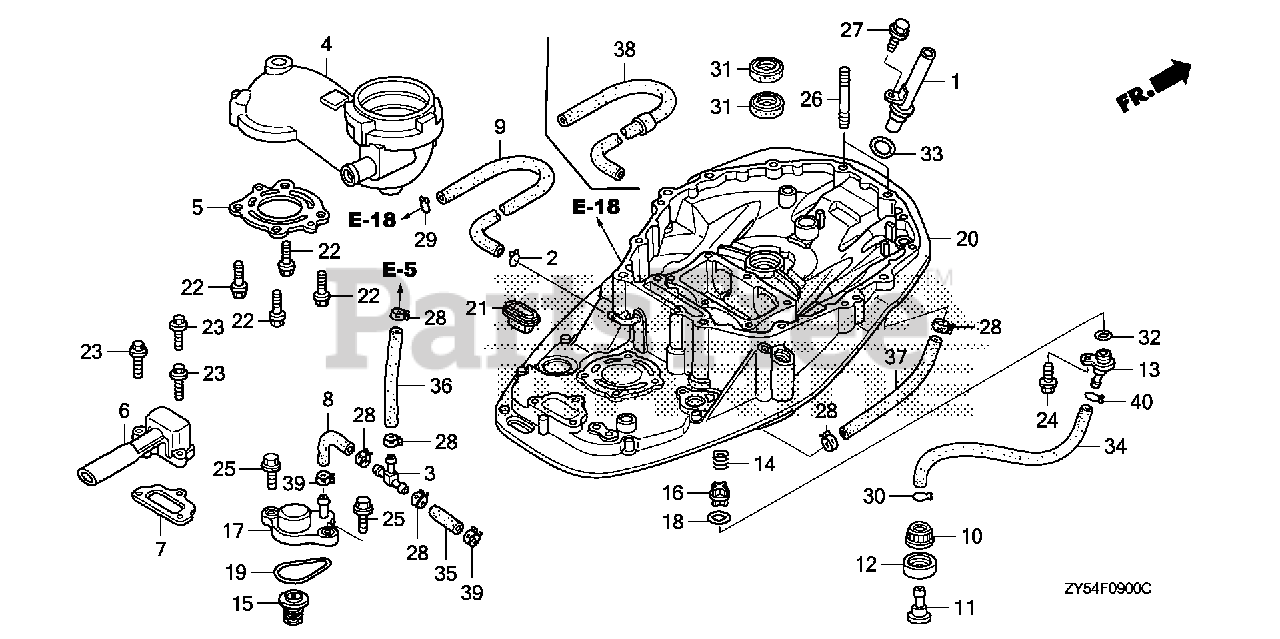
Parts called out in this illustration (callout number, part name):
1	PIPE, OIL LEVEL
2	CLIP, TUBE (ENGINE NO.)
4	GUIDE, EX. *NH8* (DARK GRAY)
5	GASKET, EX. GUIDE
6	PORT, IDLE EX.
7	GASKET, IDLE EX. PORT
8	TUBE, WATER RELIEF
10	NUT, WATER MOUTH
11	JOINT, WATER HOSE
12	SEAT, WATER MOUTH
13	COVER, FLUSH VALVE *NH8* (DARK GRAY)
13	COVER, FLUSH VALVE
13	COVER, FLUSH VLV
14	SPRING, FLUSH VALVE
15	VALVE ASSY., RELIEF
16	VALVE, FLUSH
17	COVER, RELIEF VALVE
18	GASKET, FLUSH VALVE
19	O-RING, THERMOSTAT COVER
20	CASE, MOUNT *NH8* (DARK GRAY)
21	RUBBER, MOUNT CASE SEAL
22	BOLT, FLANGE (8X30)
23	BOLT, FLANGE (6X25)
24	BOLT, FLANGE (6X16)
24	BOLT, FLANGE (6X20) (ENGINE NO.)
25	BOLT, FLANGE (6X22)
26	BOLT, STUD (10X55)
27	BOLT, FLANGE (6X12)
28	CLAMP, TUBE (D10.5) (ENGINE NO.)
29	CLIP, TUBE (B12)
30	CLIP B1, TUBE
31	SEAL, WATER (22X35X7)
32	O-RING (16MM)
33	O-RING (11.5X3.5)
34	BULK HOSE, FUEL (8X1000) (95001-80001-(95001-80001-60M)
35	BULK HOSE, VACUUM (7X3000) (7X550)
36	BULK HOSE, VACUUM (7X3000) (7X550)
37	BULK HOSE, VACUUM (7X3000) (7X550)
38	TUBE F, WATER
39	CLAMP, TUBE (D10.5) (ENGINE NO.)
40	CLIP B1, TUBE
